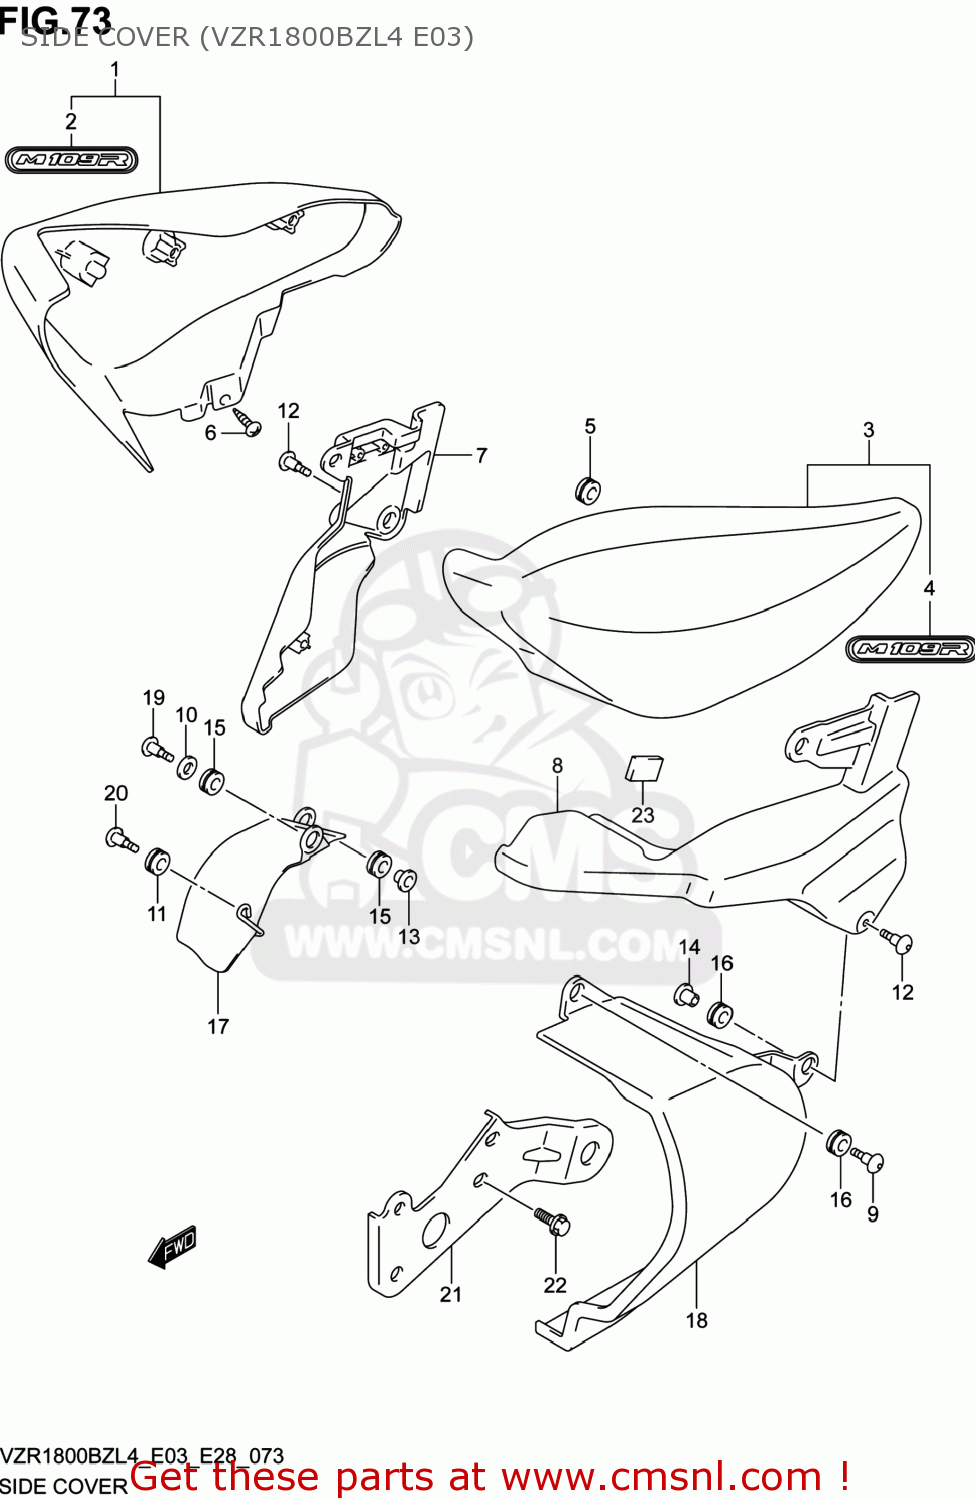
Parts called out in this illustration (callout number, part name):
1	COVER,SIDE,R(BLACK)
2	EMBLEM,M109R
3	COVER,SIDE,L(BLACK)
4	EMBLEM,M109R
5	CUSHION
6	SCREW
7	COVER,SIDE LWR,R
8	COVER,SIDE LWR,L
9	SCREW(6X20)
10	WASHER(10.5X20X2.3)
11	CUSHION
12	SCREW(6X25)
13	SPACER(6.5X10X11.6)
14	WASHER
15	CUSHION
16	CUSHION
17	COVER,LOWER,R
18	COVER,LOWER,L
19	SCREW(6X20)
20	SCREW(6X20)
21	BRACKET,LWR COVER,L
22	BOLT
23	CUSHION,FRAME COVER
